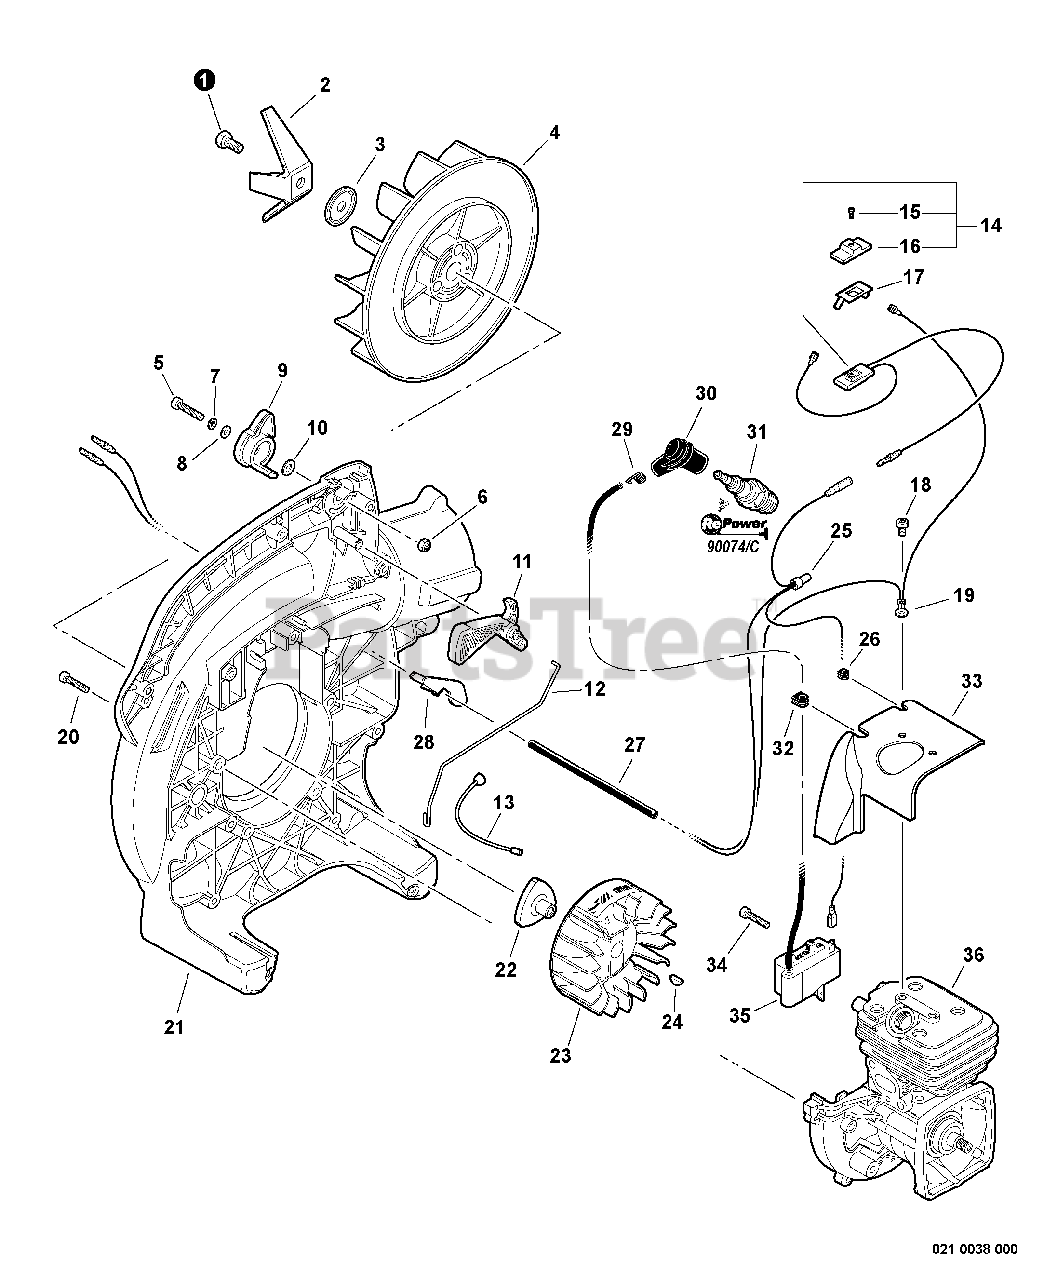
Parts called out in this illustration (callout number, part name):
1	SCREW - 8X15
2	CUTTER, SHREDDER
3	WASHER - CUP
5	SCREW - 5X25
6	LOCKNUT - 5
7	LOCKWASHER - 5
8	WASHER - 5
9	LEVER, THROTTLE
10	WASHER - 5
11	TRIGGER, THROTTLE
12	ROD, THROTTLE
13	CABLE, THROTTLE
14	IGNITION SWITCH ASSY
15	SCREW - 3X10
16	KNOB, SWITCH - ORANGE
17	TERMINAL - GROUND
18	SCREW - 5X8
19	LEAD - GROUND
20	SCREW - 4X20
21	COVER, FAN - RIGHT
22	HUB, FAN
23	FLYWHEEL
25	LEAD - IGNITION
27	TUBE, INSULATOR
29	TERMINAL, SPARK PLUG CAP
30	CAP, SPARK PLUG
31	SPARK PLUG -- BPM-8Y
31	SPARK PLUG -- BPMR-8Y
33	SHIELD, CYLINDER
34	SCREW - 4X20
35	COIL, IGNITION
36	SHORT BLOCK -- SB1104
37	RePower TUNE-UP KIT
